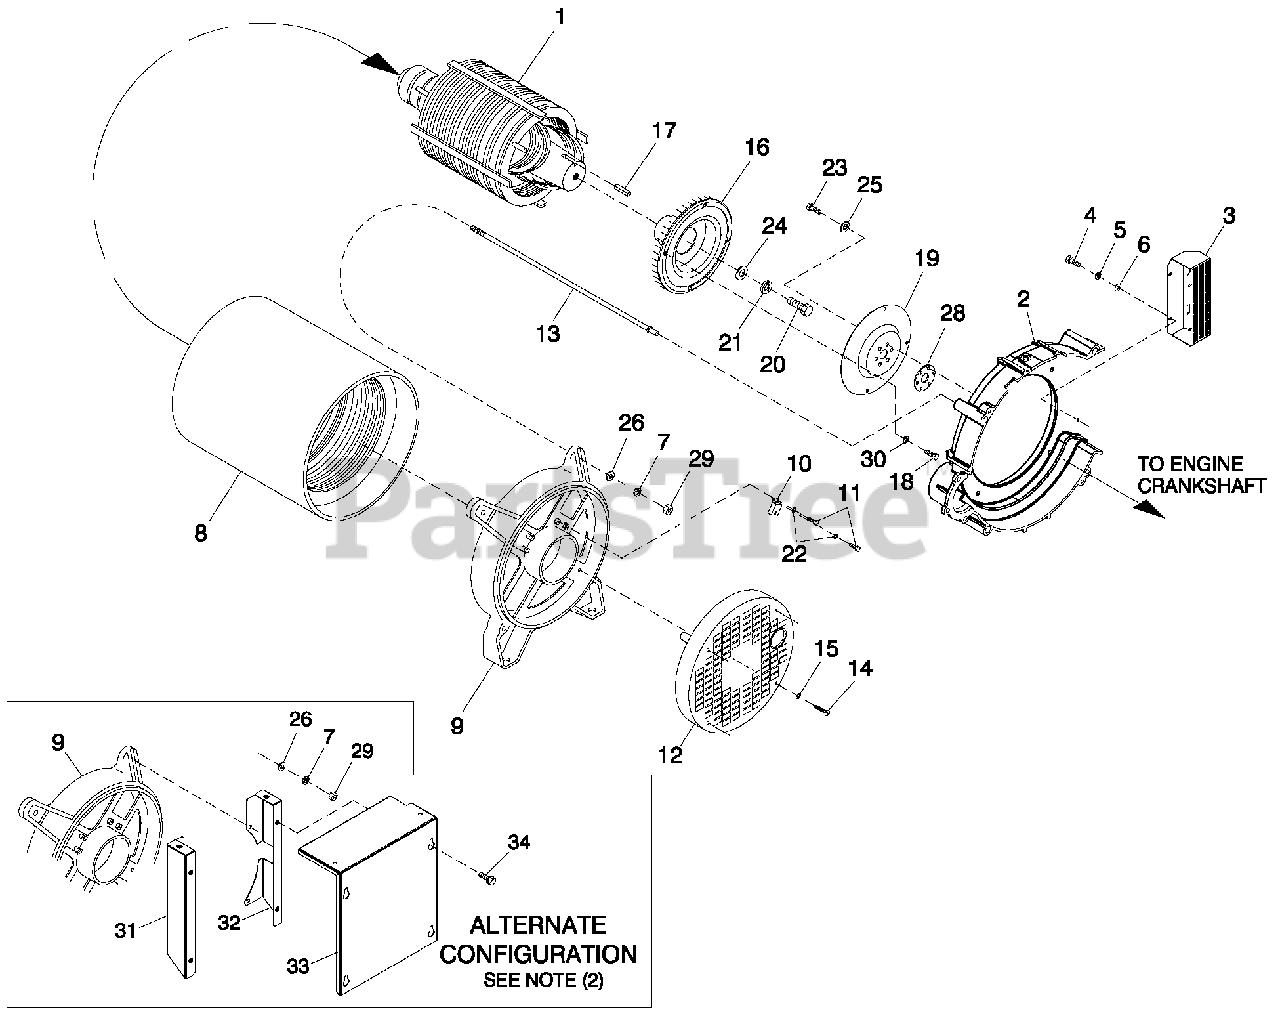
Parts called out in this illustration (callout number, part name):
1	A SSY RTR 104 KD1 HI EFF (18KW)
2	HOUSING BLOWER LG PILOT
3	BLOWER HOUSING SCREEN
4	SCREW PPHMM5-0.8X 8 ZINC
5	WASHER LOCK M5
6	WASHER FLAT M5
7	WASHER LOCK M8-5/16
8	A SSY STR 104-18AD1 HI EFF (18KW)
9	BEARING CARRIER REAR LG PILOT
10	A SSY HOLDER BRUSH
11	SCREW HHC M4-0.7 X 16 G8.8
12	COVER REAR BEARING
13	STUD M8-1.25 475 LONG
14	SCREW RHM #10-24X2
15	WASHER LOCK #10
16	FLYWHEEL & RINGGEAR A SSY 1.6L
17	KEY SQ 3/8X1 STEEL
18	SCREW HHFC M10-1.5 X 16 C10.9
19	PLATE FLEX 1.6L R12.7
20	SCREW HHC M12-1.75X 35 G8.8
21	WASHER LOCK M12
22	WASHER SHAKEPROOF INT #8
23	SCREW HHC M10-1.0X 20 G10.9
24	SPACER ROTOR SHAFT
25	WASHER .41 ID .94OD.12THK
26	WASHER FLAT .34 ID X .75 OD
28	PLATE SPACER 14GA 1.6L (TO BE USED WITH ENGINE PLATE P/N 0G0834.)
29	NUT HEX M8-1.25 G8 CLEAR ZINC
30	WASHER LOCK M10 RIBBED ZINC
31	SUPPORT LH ALT COVER
32	SUPPORT RH ALT COVER
33	COVER REAR 10" ALT
34	SCREW HWHT M6-1 X 16 N WAZ/JS
